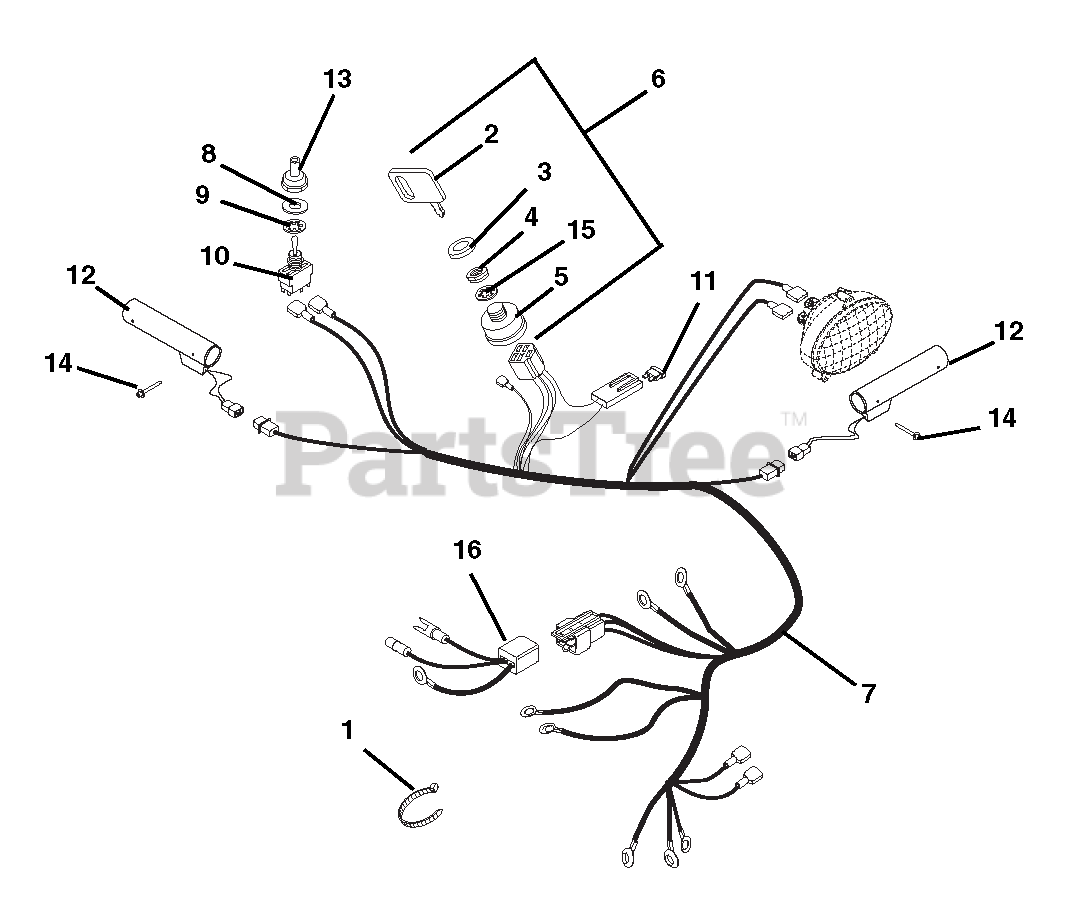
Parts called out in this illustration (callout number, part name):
1	CABLE TIE LG 5-1/2
2	KEY -W/CAP
3	CAP - IGNITION SWITCH
4	NUT-PANEL .625-32 GRECO
5	IGNITION SWITCH ASSEMBLY
6	SWITCH ASSEMBLY
7	HARNESS, LIGHT&HW, 2 PIN W/GRD
8	WSHR-FL-STL .505X.875X.024 PL
9	WSHR-LK-INT .563X.040 YWZC
10	SWITCH, ON/OFF
11	FUSE, 15 AMP.
12	HEATED GRIP, MAGURA
13	BOOT, SWITCH
14	RVT-POP #43 .125X.313 STL ZINC
15	WSHR-LK-INT .625X.045 YWZC
16	HARNESS ADAPTER, BRIGGS 12V
